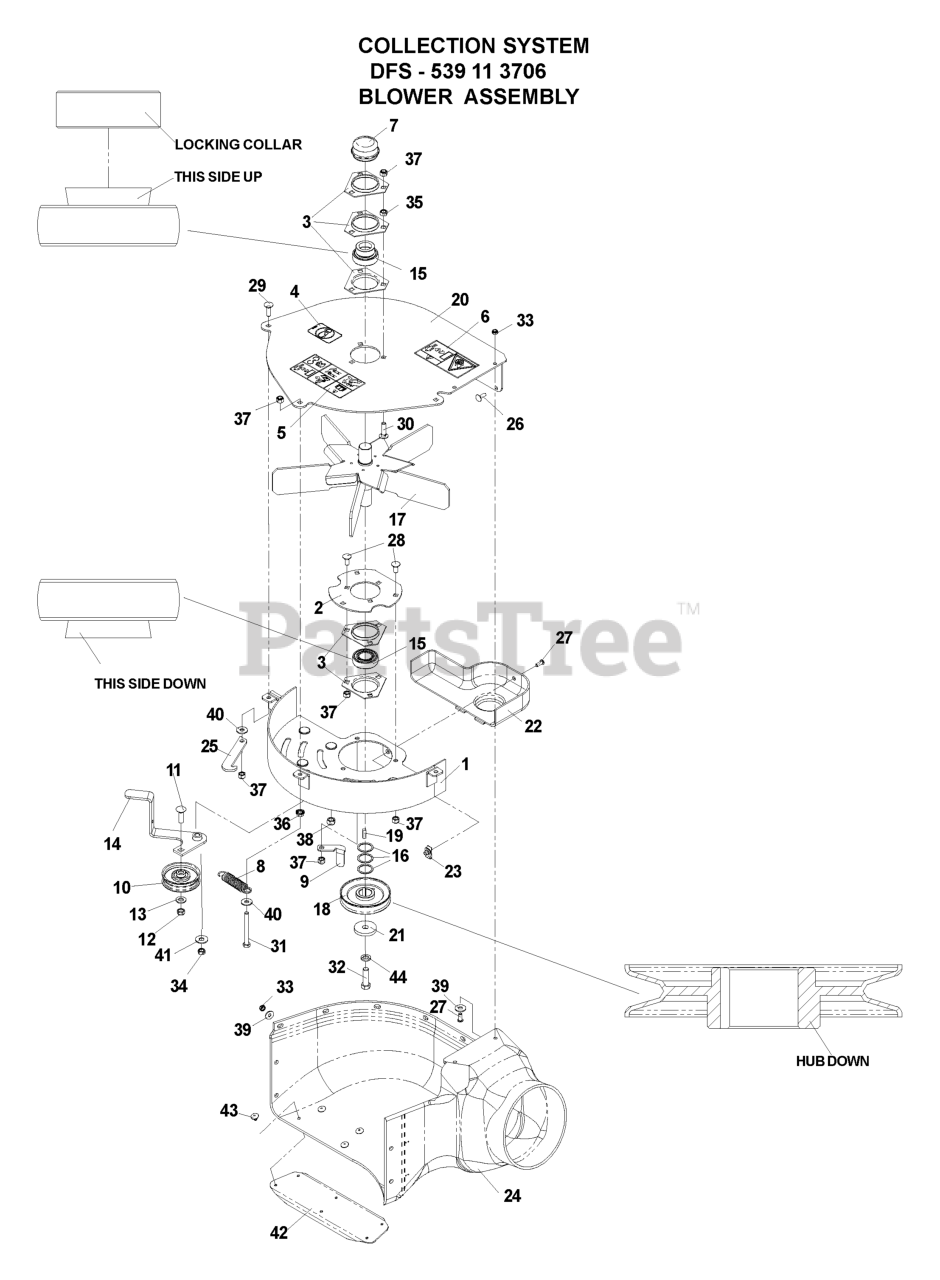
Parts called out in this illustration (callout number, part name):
1	FLOOR WELDMENT
2	BEARING PLATE
3	BRG FLANGE
4	DECAL, NO STEP
5	DECAL, EURO WARNING
6	EURO DECAL, IMPELLER
7	GREASE CAP
8	SPRING-TRANS
9	BELT GUIDE
11	RHSNB 3/8-16 X 1-1/4
12	NUT HEX 3/8-16 NYLON, THIN
13	WASHER 3/8 SAE FLAT
15	BEARING KIT-2 PCS
16	BUSHING.MACHINE.18.GAUGE
17	SPINDLE BLOWER FAN
19	KEY 1/4 SQ X 3/4
20	FAN COVER W/DECALS
21	SPINDLE WASHER
22	PULLEY SHEILD
23	1/4C - U TYPE RETAINER
24	BLOWER HOUSING
25	KEEPER, IDLER
26	RHSNB 1/4C X 3/4
27	SCR 1/4-20 X 5/8 BTN SKT HD ZD
28	RHSNB, 5/16 X 3/4
29	RHSNB 5/16C X 1
30	BOLT, CARRIAGE 5/16X1-1/4
31	HCS 5/16C X 2-3/4
32	HCS 7/16F X 1 1/2
33	JAM NUT 1/4C (2 2 PW01)
34	NUT, 5/16C, CENTERLOCK
35	NUT 5/16C HEX
36	NUT 5/16C WHIZ
37	NUT 5/16 NYLOC
38	NUT 3/8-16 NYLOC
39	WASHER 1/4 FLAT
40	WASHER 5/16 FLAT
41	WASHER 3/8 FLAT
42	BLOWER SUPPORT
43	RIVET E/16 X 1/4 LG FLG
44	WASHER 7/16 LOCK
539113706	Blower Assembly (DFS)
